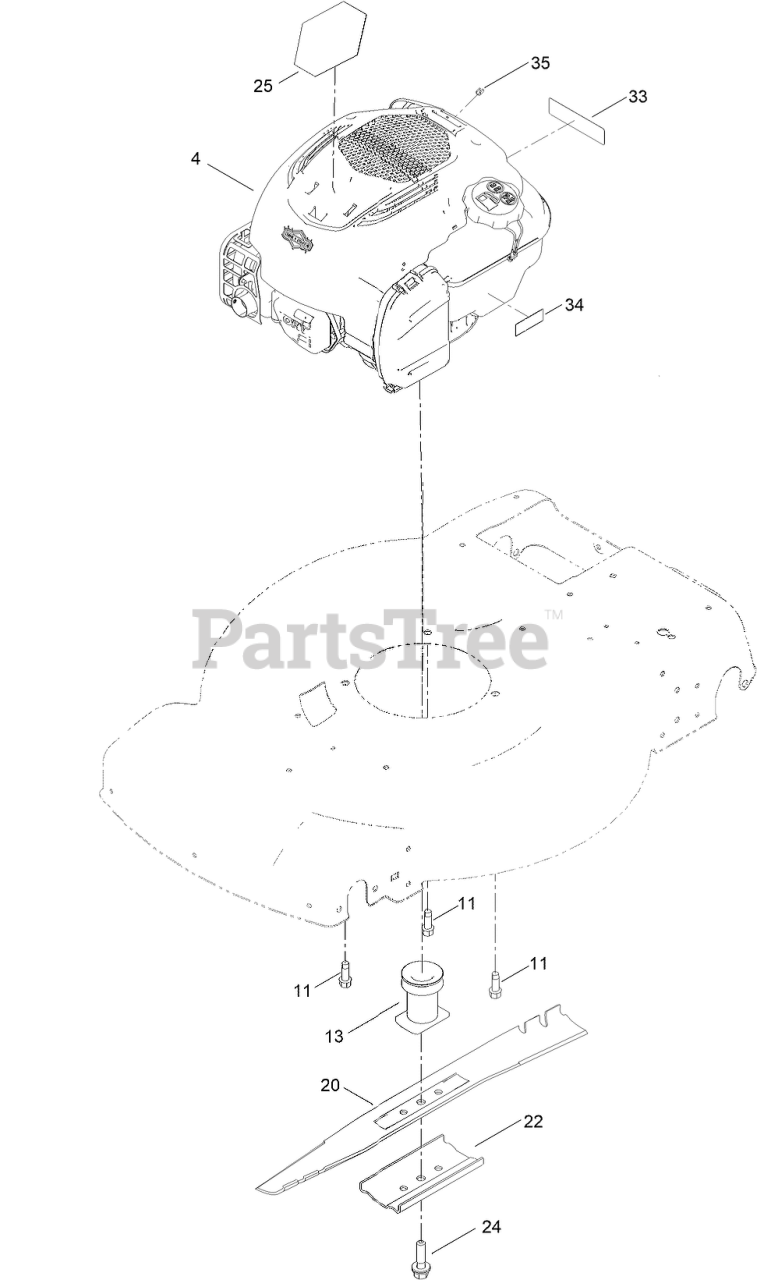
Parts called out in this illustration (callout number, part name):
4	ENGINE-BRIGGS, 625 EXI ZS SS
11	SCREW-THD FORM, HWH
13	DRIVER-BLADE
20	BLADE-22 INCH
22	SUPPORT-BLADE
24	BOLT-BLADE
25	DECAL-BRIGGS 625 EXI SS
33	DECAL-ARRESTOR, SPARK
34	DECAL-LEVEL, FUEL
35	STOP-ROPE
